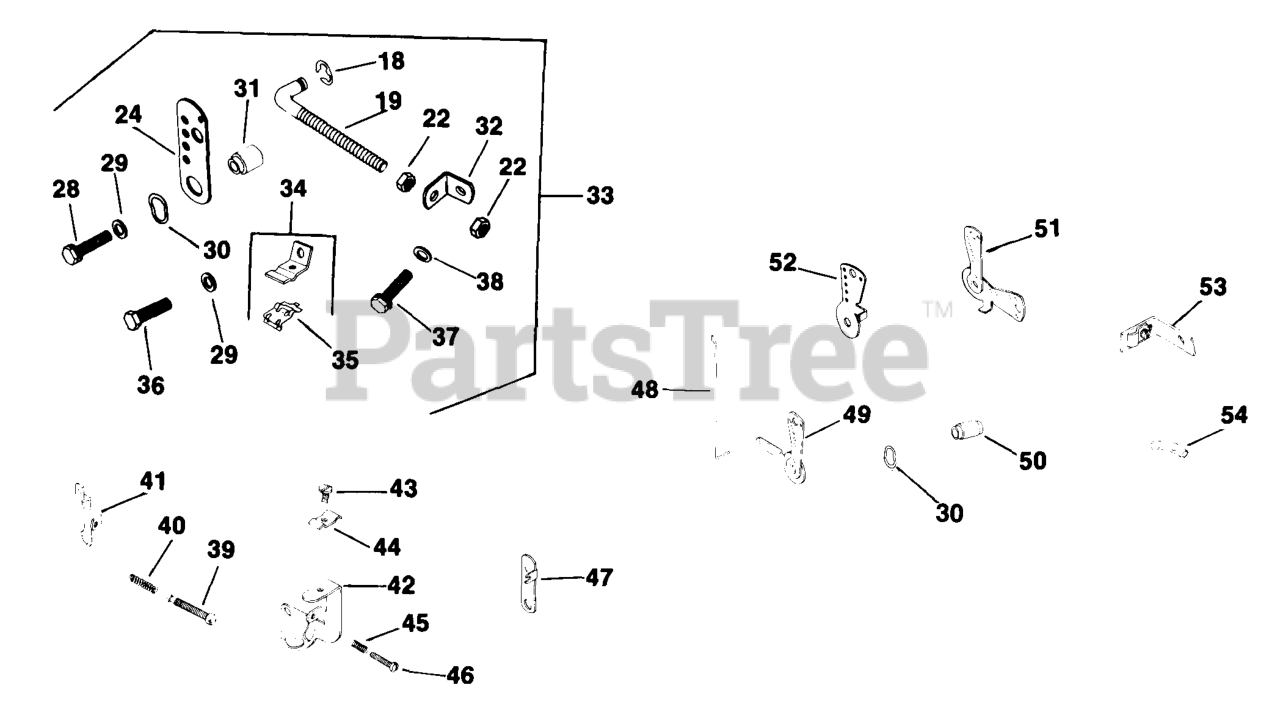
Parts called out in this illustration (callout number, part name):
18	RETAINER
19	ROD-(#DSC)
22	NUT, MACH SCREW #10-32 GRD 2 USE 25 100 18-S
29	WASHER, FLAT 1/4" (O.D. 1/2")
30	WASHER, SPRING 11/32"
31	SPACER - DISCONTINUED
39	SCREW - DISCONTINUED
